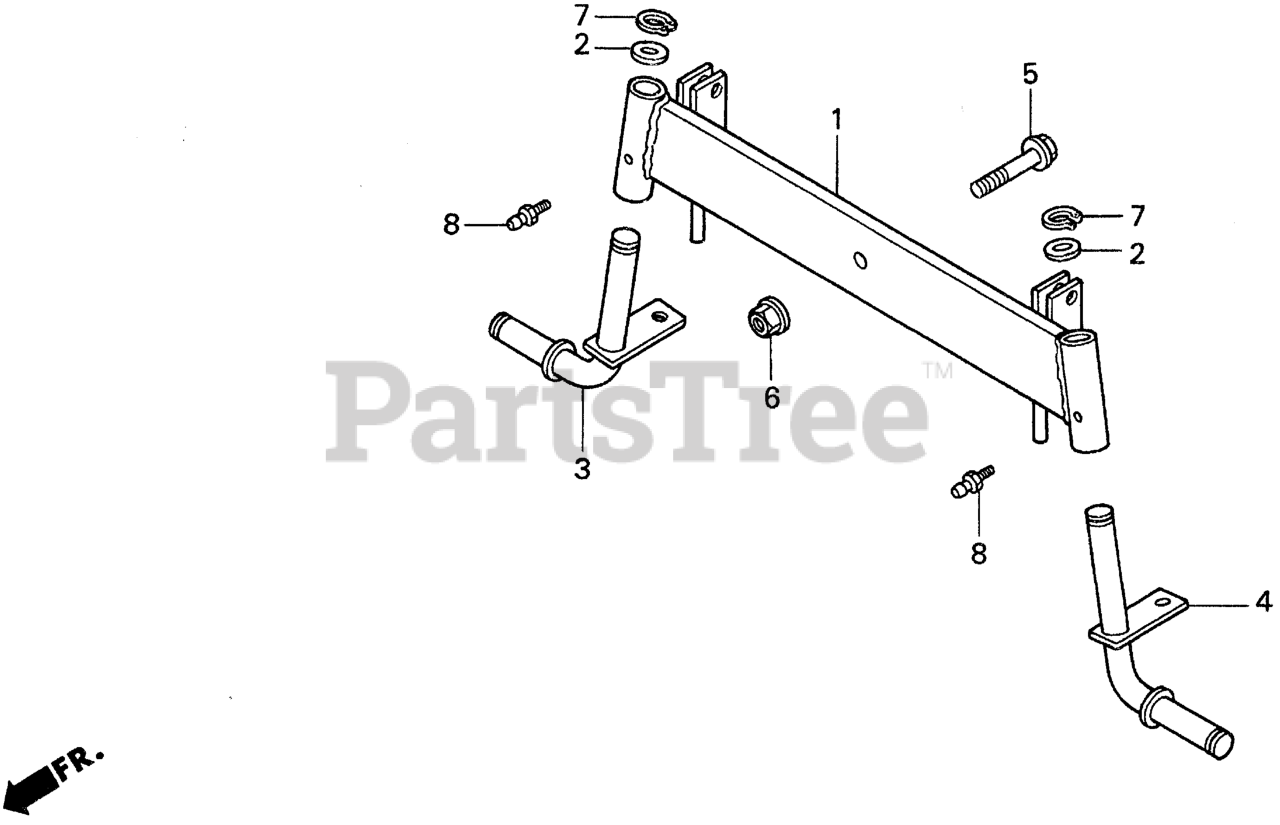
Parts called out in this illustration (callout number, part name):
2	PLATE, PILLION STEP SIDE
3	KNUCKLE, R.
4	KNUCKLE, L.
5	BOLT, FLANGE (12X50)
6	NUT, SELF-LOCK (12MM)
7	CIRCLIP, EX. (3/4")
8	NIPPLE, GREASE (A.T6) (M6X1.0)
